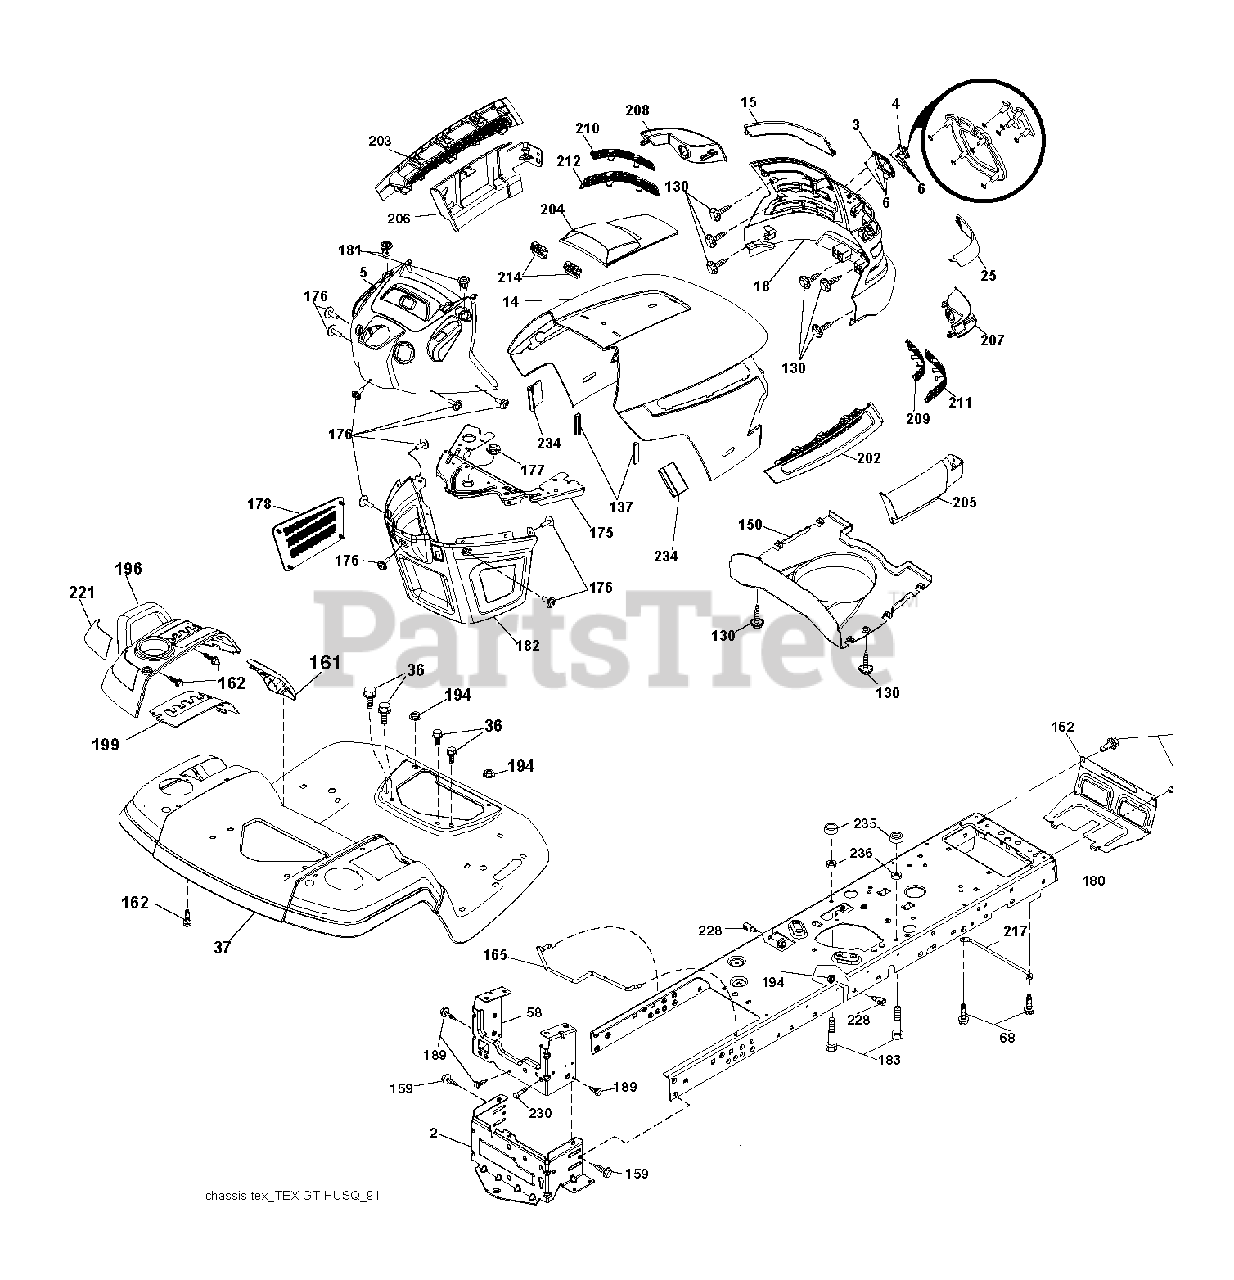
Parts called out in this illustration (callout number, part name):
2	DRAWBAR.LOWER.2PC.18/22
3	TRIM.HUSQ.TG/CRD.SERVICE
4	RP LOGO
5	DASH.ASM.HUSQ.GT
6	NUT PUSH M
14	HOOD
15	LENS.LH.TEX.GT.HUSQ.CL
18	GRILL.ASM.HUSQ.TG/CRD.W/TRIM
25	LENS.RH.TEX.GT.HUSQ.CL
36	SCREW 5/16"
37	FENDER.PNT.TX.GT.CH/FW.ORANGE
58	DRAWBAR.UPPER.2PC,LRG.FENDER
68	SCREW LT
130	SCREW.#10 X 0.750.BOS
137	BUMPER DASH
150	AIR.DUCT.HOOD.TEX.GT.HUSQ
152	SHIELD.BROWNING/DEBRIS
159	SCREW, 3/8-16X3/4
161	CONSOLE.FUEL.WINDOW.HU
162	SCREW.HI-LO.CONSOLE
165	SUPPORT.TANK.REAR.B/TE
175	PLATE.CROSSMEMBER.HUSQ
176	SCREW.#10-24X5/8.RN.QU
177	BUSHING, STEERING
178	CARGO.ASM.NET.TXGT.W/C
180	CHASSIS.STAMPING.LT/GT
181	BUSHING.MNT.FEND.CRGO.
182	DASH.LOWER.COMMON.12V.ADAPTOR
183	BOLT.5/16-18X1-1/4 FULL THD
189	SCREW
194	NUT LOCK HEX FLANGE 5/16-18
196	CONSOLE.ASM.DCKLFT.W/RF.HQ.DLR
199	PLATE.DECK.LIFT.HUSQVARNA.GT
202	VENT.SIDE.HOOD.RH.HUSQ
203	VENT,SIDE.HOOD.LH.HUSQ
204	HOOD VENT
205	HOOD SIDE SKIRT RH
206	SKIRT.HOOD.SIDE.HUSQ.L
207	BEZEL.RH.TEX.GT.HUSQ
208	BEZEL.LH.TEX.GT.HUSQ
209	INSERT.HEX.GRILL.HUSQ.GREY
210	INSERT.HEX.GRILL.HUSQ.
211	INSERT.HEX.GRILL.HUSQ.
212	INSERT.HEX.GRILL.HUSQ.
214	CLIP.RETAINER.TINNER.
217	ROD.PIVOT.HOOD
221	REFLECTOR.LH.TEX GT HU
228	STUD.FASTNER.W/ANTI-ROTATE
234	BUMPER.HOOD.TEX.HUSQVARNA
235	SPACER FENDER
236	NUT.CENTERLOCK.5/16-
